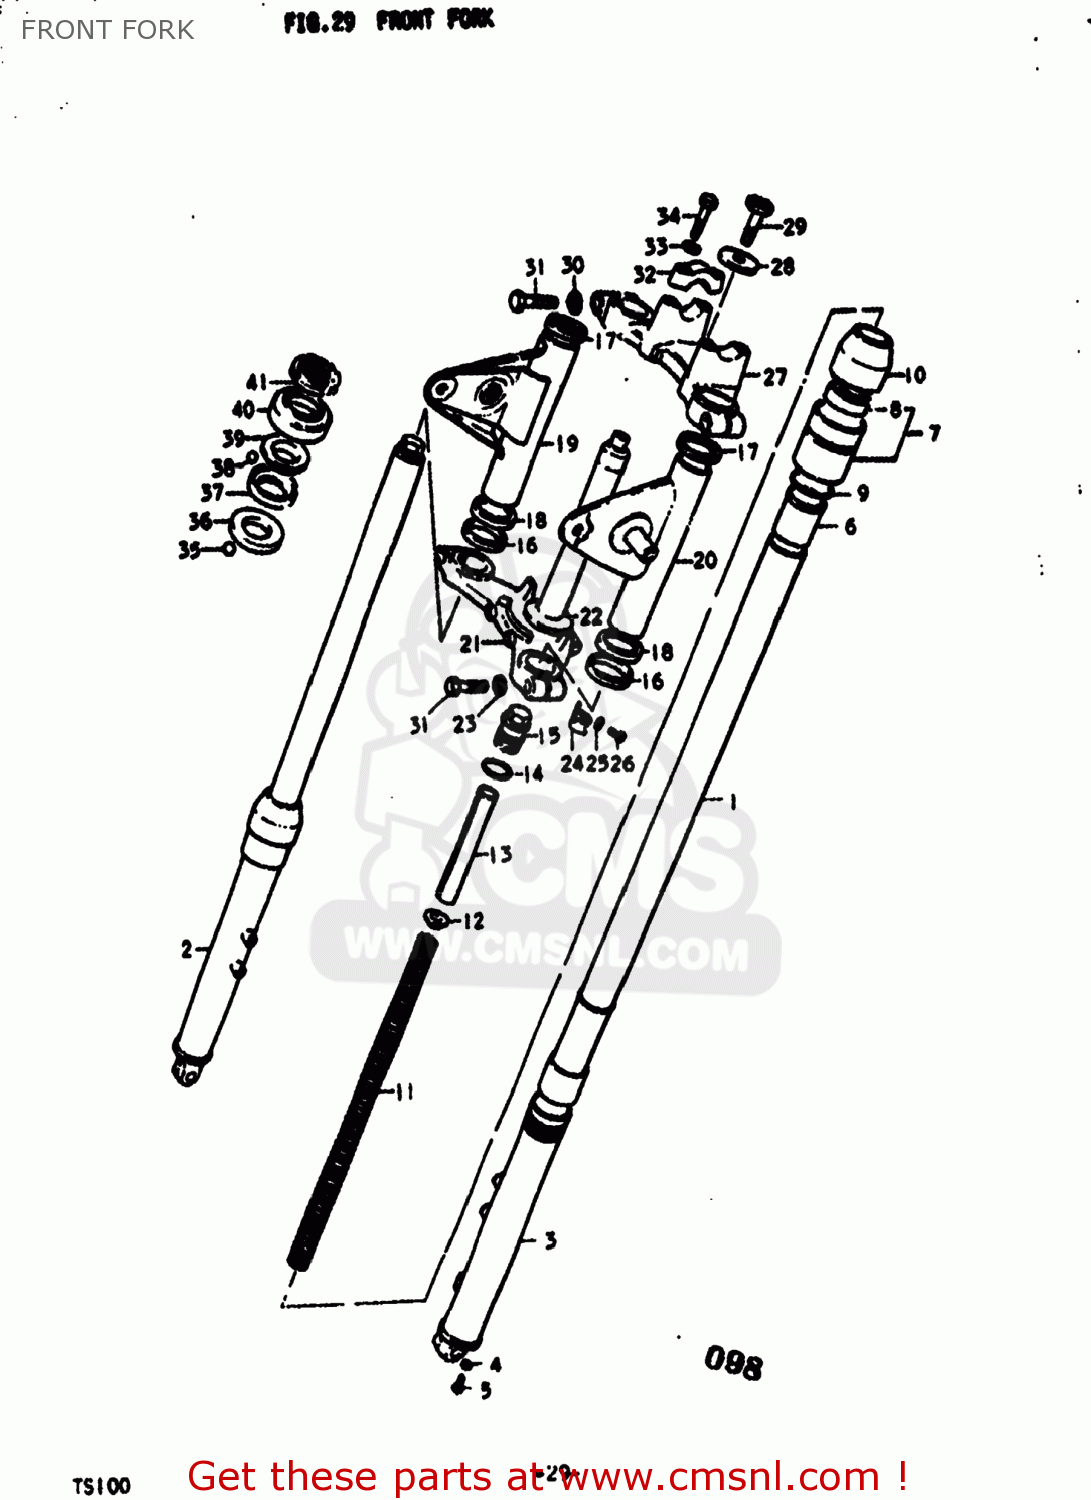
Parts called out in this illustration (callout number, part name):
0	DAMPER SET
1	TUBE,INNER
2	TUBE,OUTER,LEFT
3	SEAL,OIL
4	RING,SNAP
5	WASHER,FRONT FORK
6	STUD BOLT
7	GASKET,DRAIN,PLUG (NAS)
8	SCREW
9	SNAP RING
10	PISTON
11	CYLINDER,FRONT FORK
12	PIECE,OIL LOCK
13	SEAL,DUST
14	O-RING,FORK INNER TUBE
15	STEM,STEERING
16	RACE,STEERING OUTER LWR
17	SPRING
18	GUIDE,SPRING
19	SPACER,SPRING
20	BRACKET,HEADLAMP HOUSING
21	BRACKET,HEADLAMP,LEFT
22	BRACKET,HEADLAMP HOUSING
23	BRACKET,HEADLAMP,LEFT
24	GASKET
25	SEAT,HEADLAMP BRACKET
26	GUIDE, COVER
27	CUSHION,HEADLAMP BRACKET
29	HEAD,STEERING STEM
30	HOLDER,HANDLEBAR
31	BOLT,FR FORK
32	CLIP
33	SCREW
34	LOCK WASHER
35	BOLT,FORK INNER TUBE
36	BOLT
37	Bolt
38	LOCK WASHER
39	WASHER,STEM HEAD(10.5X30X3.2)
40	CUSHION,HEAD LAMP BRACKET
41	NUT (8MM)
42	BOLT,FORK INNER TUBE F
43	LOCK WASHER
44	CLIP
45	BOLT,FR FORK LWR(12X33)
46	WASHER,LOCK 12
47	HOLDER,AXLE
48	LOCK WASHER
